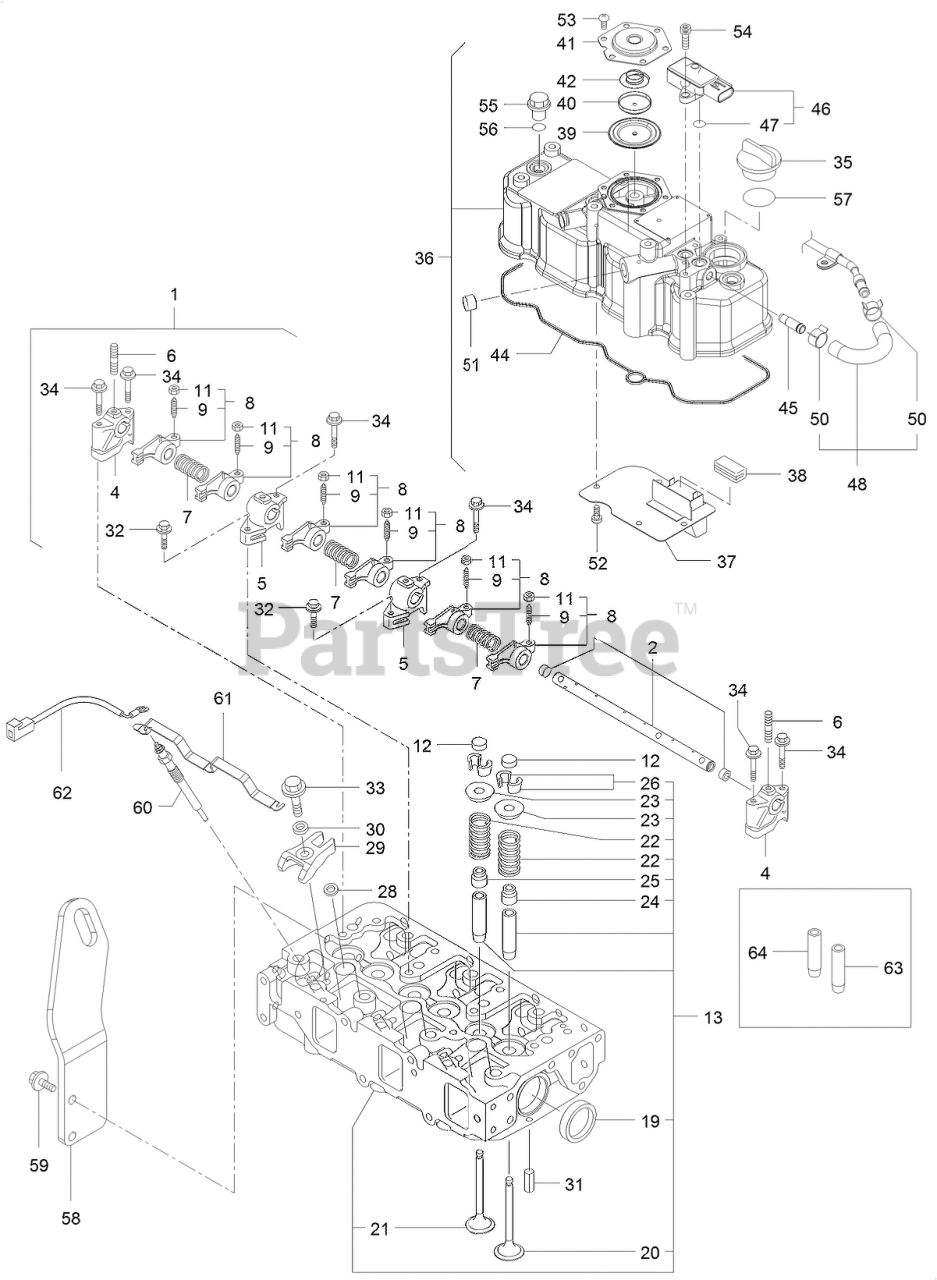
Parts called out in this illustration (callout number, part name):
1	SHAFT ASM
4	Support
5	Support
6	BOLT,STUD
8	Arm-Rocker
9	SCREW-ADJUST, VALVE
12	Cap-Valve
13	CYLINDER HEAD ASM
23	Retainer-Spring
24	SEAL-STEM, VALVE
25	SEAL-STEM, VALVE
26	PIN-COTTER
28	GASKET-INJECTOR
29	Retainer-Injector
30	WASHER-INJECTOR
31	PIN-SPRING
35	COVER-FILLER
36	CYLINDER HEAD COVER ASM
39	DIAPHRAGM
41	PLATE-BREATHER
42	SPRING-DIAPHRAGM
44	GASKET-HEAD, CYLINDER
46	SENSOR-PRESSURE
47	O RING-SENSOR, PRESSURE
48	HOSE ASM
50	Clip-Hose
58	LIFTER-ENGINE
59	BOLT
60	PLUG-GLOW
61	CONNECTOR-PLUG, GLOW
62	HARNESS-WIRE
64	GUIDE-VALVE
